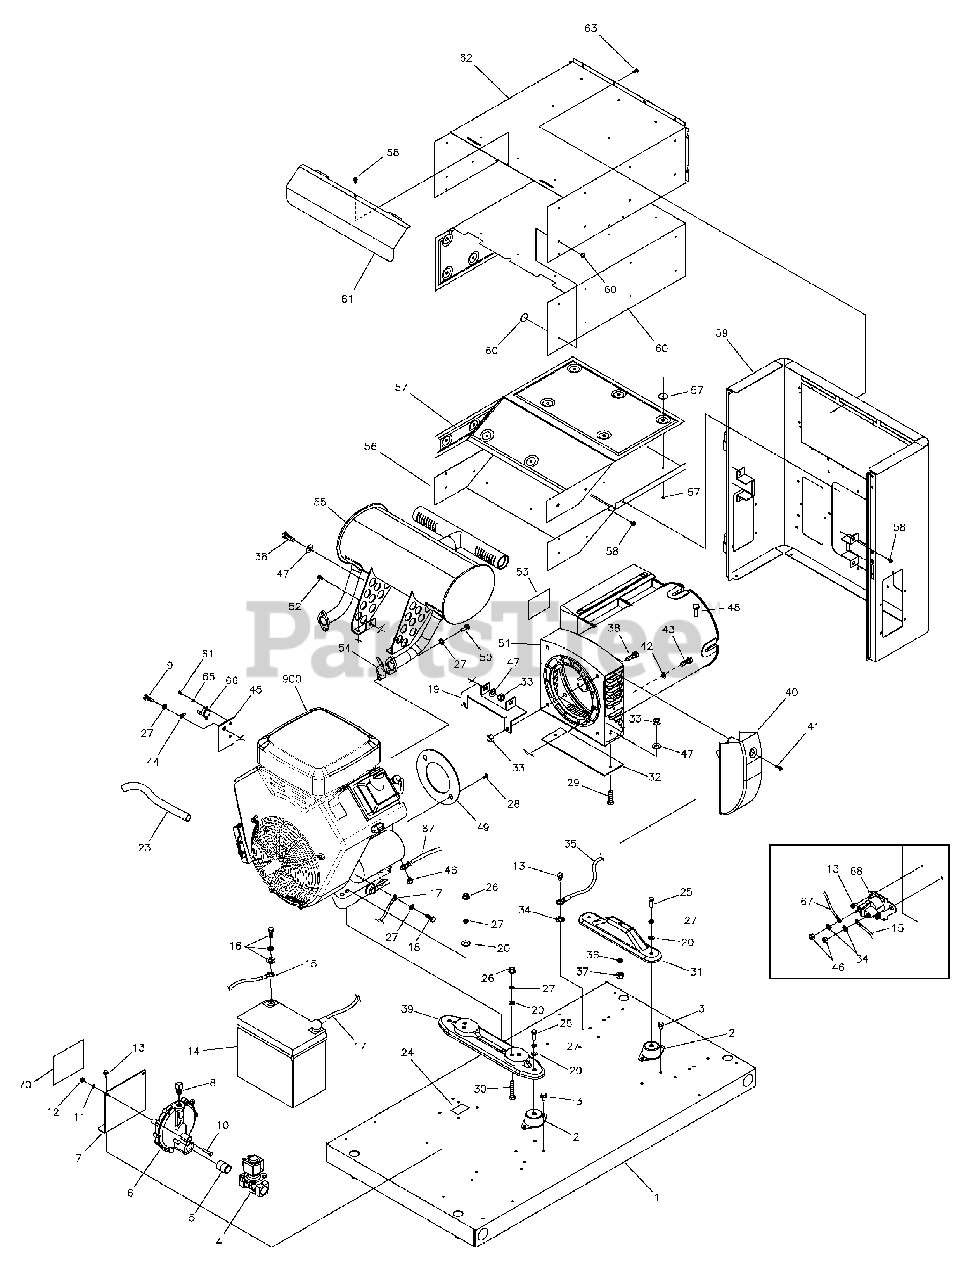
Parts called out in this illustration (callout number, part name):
1	BASE, Mounting
2	MOUNT, Vibration
4	SOLENOID, Gas Fuel
5	FITTING, Coupling
6	REGULATOR, NG/LPG
7	BRACKET, Mounting, Solenoid
8	FITTING, 3/4 Flare to 3/8 NPT
9	* CAPSCREW, Hex Head, M8-1.25 x 12
10	* CAPSCREW, Hex Head, M6-1 x 30
11	* WASHER, Lock, 1/4
12	* NUT, M6-1
13	BOLT
16	KIT, Battery Hardware
18	* CAPSCREW, Hex Head, M8-1.25 x 16
20	* WASHER, Flat, 5/16-M8
23	HOSE, Oil Drain
24	DECAL, Oil Drain
25	* CAPSCREW, Hex Head, 5/16-18 x 1
26	* NUT, 5/16-18
27	* WASHER, Lock, 5/16-M8
28	* CAPSCREW, Hex Head, 5/16-24 x 3/4
29	* CAPSCREW, Hex Head, 5/16-18 x 1-3/4
31	SUPPORT, Alternator
34	* WASHER, Shakeproof, M6-1/4
36	* WASHER, Lock, M10
37	* NUT, Hex, M10
38	* CAPSCREW, Hex Head, 1/4-20 x 3/4
39	SUPPORT, Alternator
42	* WASHER, Lock, 3/8
43	* CAPSCREW, Hex Head, 3/8-16 x 1-1/4
45	PLATE, Temp Switch
46	* NUT, 1/4-20
47	* WASHER, Flat, M6
48	* CAPSCREW, Hex Head, M10-1-1/2 x 30
51	ALTERNATOR (see page 6)
53	DECAL, Caution Hot Surface
58	CRIMPTITE, 10-24 x 1/2
59	BULKHEAD, Alternator
61	COLLECTOR, Muffler Box
62	BOX, Muffler Top
63	SCREW, 10-32 x 5/8
64	* SCREW, Phillips Head, 4-40 x 0.19
65	* WASHER, Lock, #4
66	SWITCH, Oil Temp
68	SOLENOID, Starter
70	DECAL, Caution Hot Surface
900	** ENGINE
